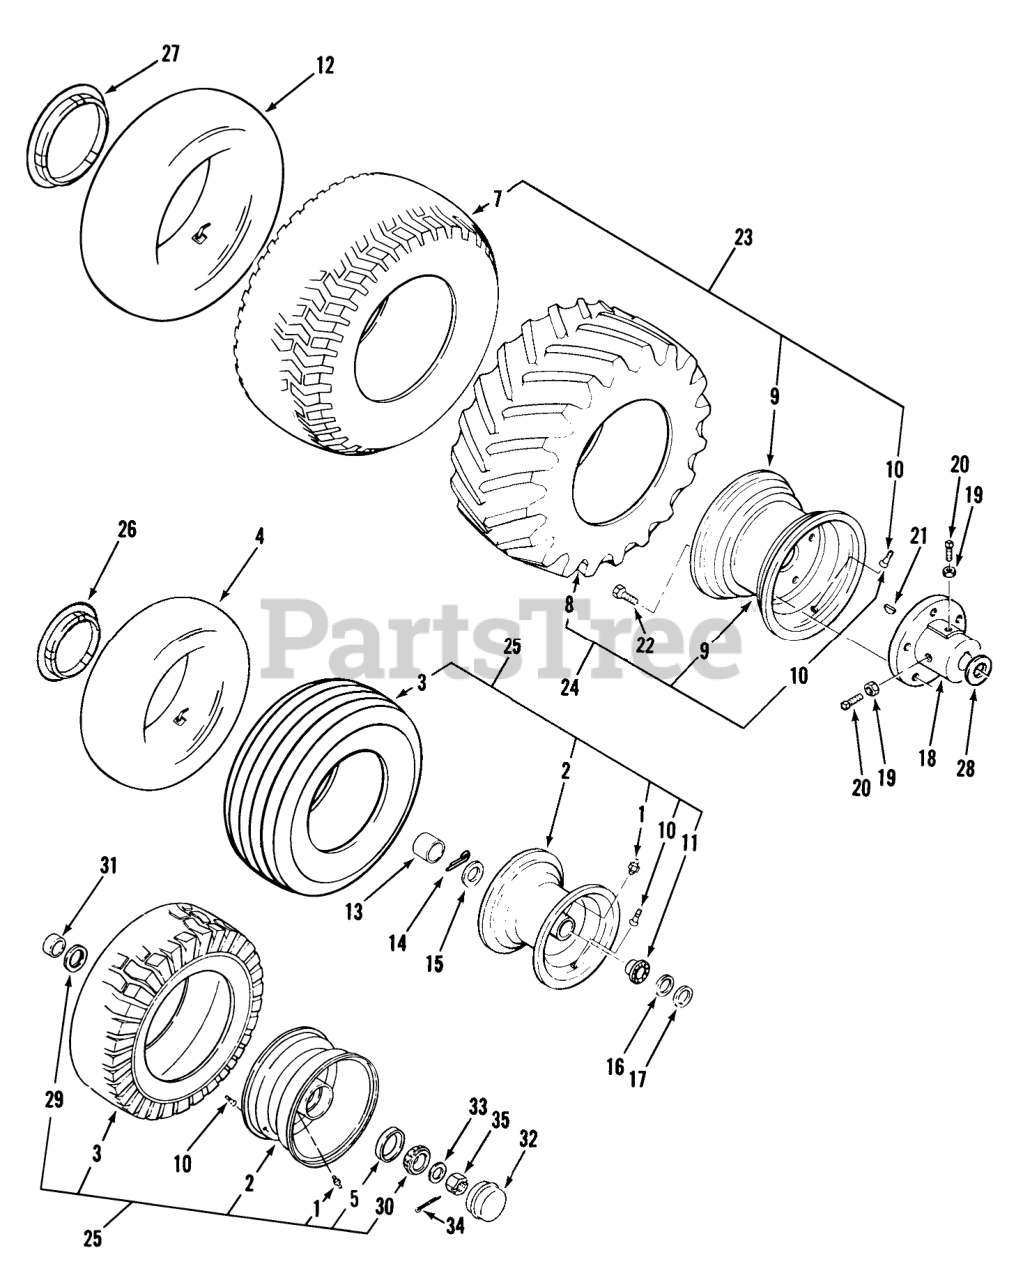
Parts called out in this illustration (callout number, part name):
1	ZERK-GREASE
2	Front Wheel (includes items 1, 10 & 11 ) 516, 518 & 520-H
2	Front Wheel (includes item 1 & qty. 1 of item 5) 520-HC
3	TIRE TURF SAVER 16X6.50-8
3	TIRE-TURF SAVER
4	TUBE-INNER
5	Cup
7	Tire
7	TIRE 9.50 X 12
7	TIRE-TURFSAVER 23X10.5-10
8	Tire-Cleat, Rear
9	WHEEL
9	RIM ASM
10	VALVE
11	BEARING-WHEEL
11	Bearing
12	TUBE-INNER
12	Rear Tube
12	Tube Cleat Tires
13	HUBCAP
14	COTTER PIN-4
15	WASHER WHEEL
16	WASHER
17	WASHER-SHIM
18	Hub Rear
19	Nut
20	Screw-Set
21	KEY-WOODRUFF
22	Lug Nut
23	Rear Wheel & Tire Assy 414
23	Rear Wheel & Tire Assy 416
23	Rear Wheel & Tire Assy 520-HC
24	ASSY WHEEL & TIRE
25	Front Wheel & Tire Assy 414, 416
25	Front Wheel & Tire Assy (includes only qty. 1 of items 30, 29 & 5) 520-HC
26	8"-HUB CAP LOGO
27	12"-HUB CAP LOGO
28	WASHER-THRUST
29	Seal
30	Bearing
31	SPACER
32	DUST CAP
33	Washer
34	Cotter Pin
35	Nut-Slotted 3/4-16
